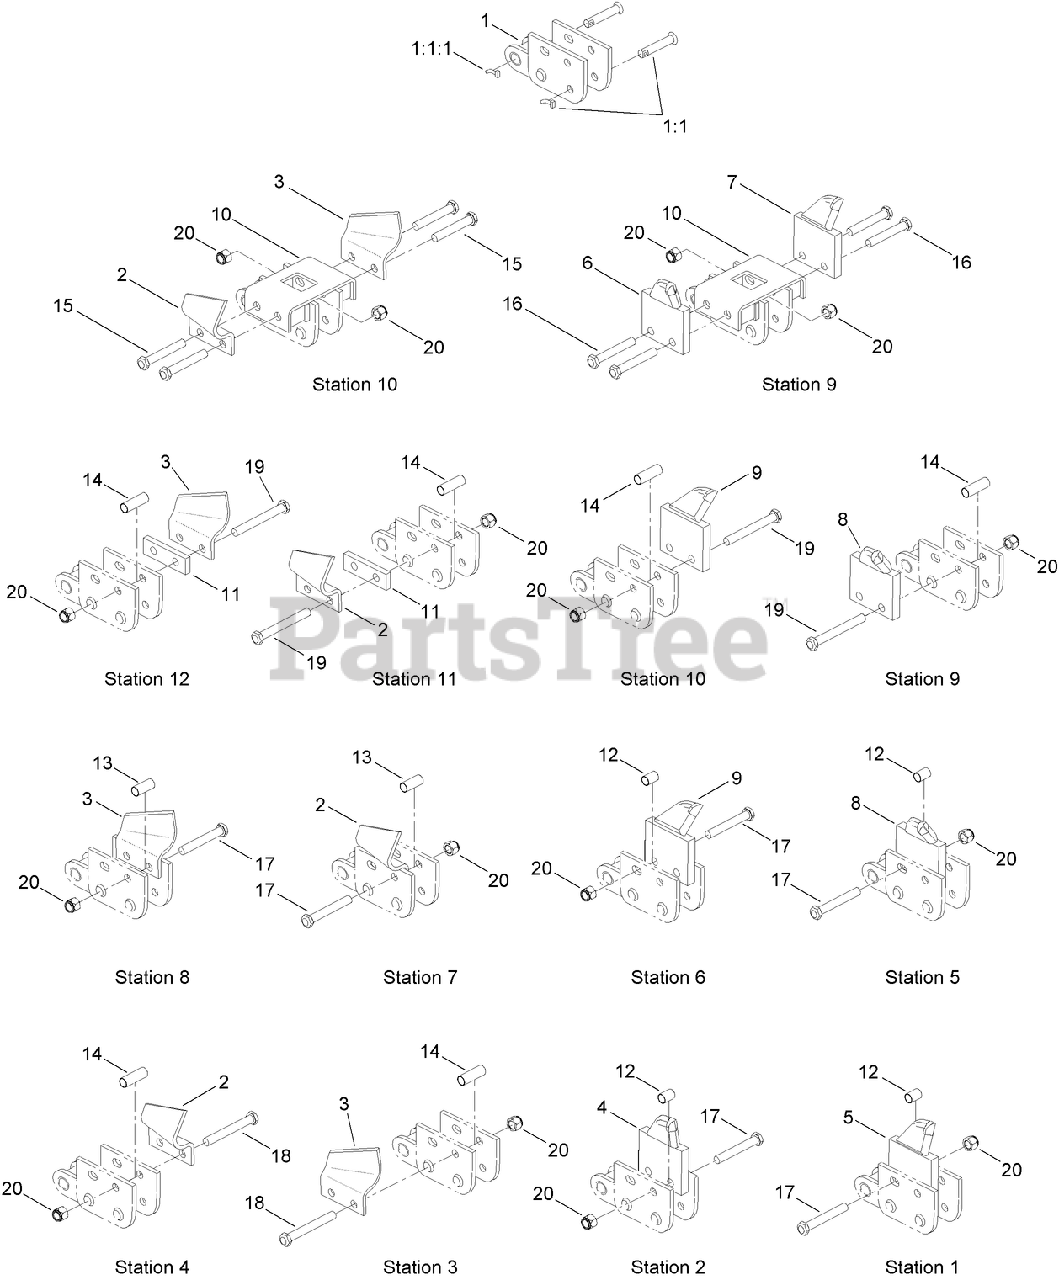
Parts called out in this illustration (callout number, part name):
1	CHAIN REPAIR LINK ASM
1:1	NOTCHED PIN AND KEEPER ASM
1:1:1	PIN-KEEPER
2	CUTTER-CUP, RH
3	CUTTER-CUP, LH
4	TOOTH-TERMINATOR, RH CENTER
5	TOOTH-TERMINATOR, LH CENTER
6	TOOTH-TERMINATOR, RH
7	TOOTH-TERMINATOR, LH
8	TOOTH-TERMINATOR, RH
9	TOOTH-TERMINATOR, LH
10	SADDLE-TOOTH SPREADER
11	SPACER-FLAT
12	SPACER-TUBE, INSIDE ADAPTER
13	SPACER-TUBE, INSIDE CUP
14	SPACER-TUBE, OUTSIDE MOUNT
15	BOLT-HH
16	BOLT-HH
17	BOLT-HH
18	BOLT-HH
19	BOLT-HH
20	NUT-LOCK
